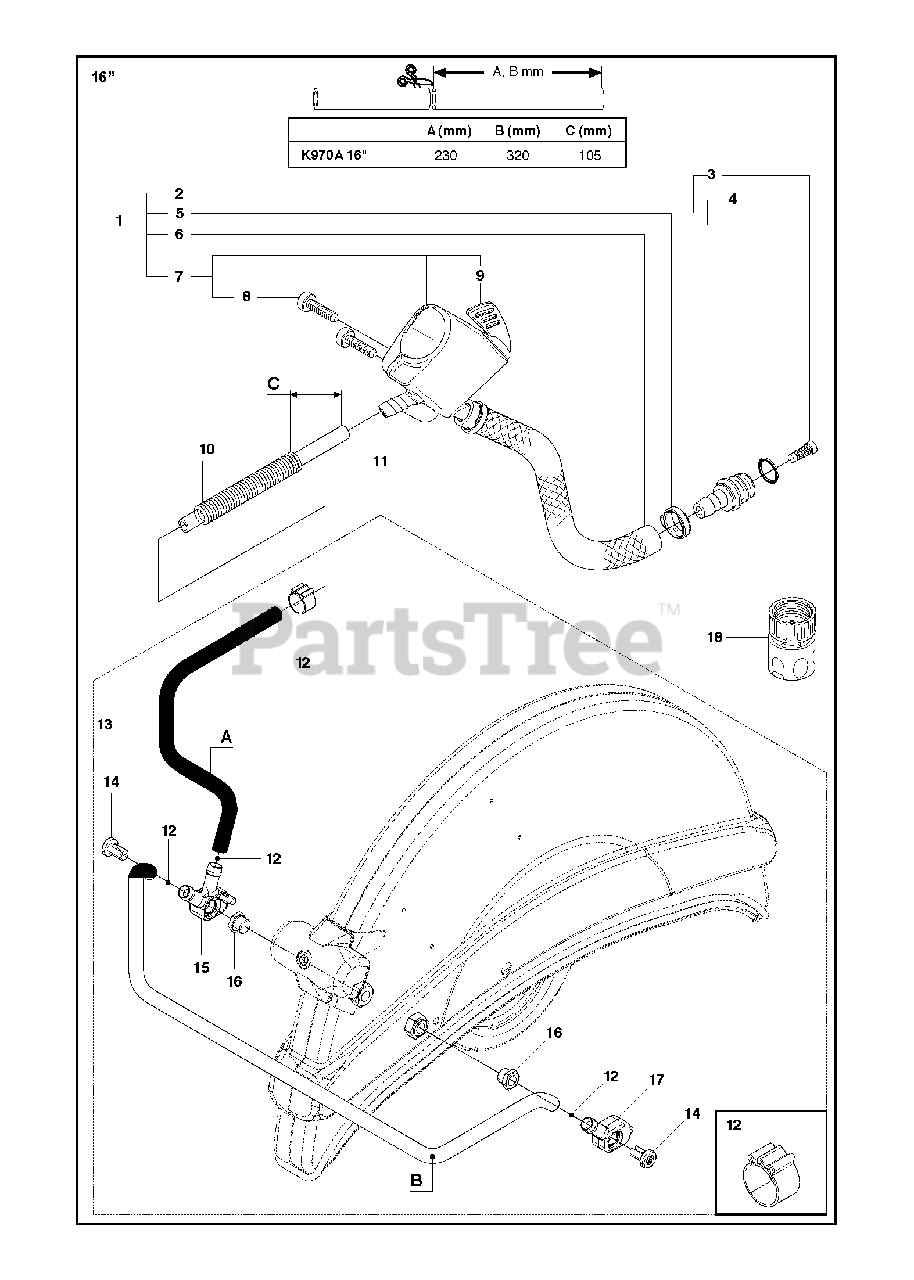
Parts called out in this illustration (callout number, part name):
5	HOSE CLAMP
8	SCREW ITXSCT
9	VALVE SPINDLE
10	PROTECTIVE SPRING
13	HOSE
14	SCREW ITXSCM
